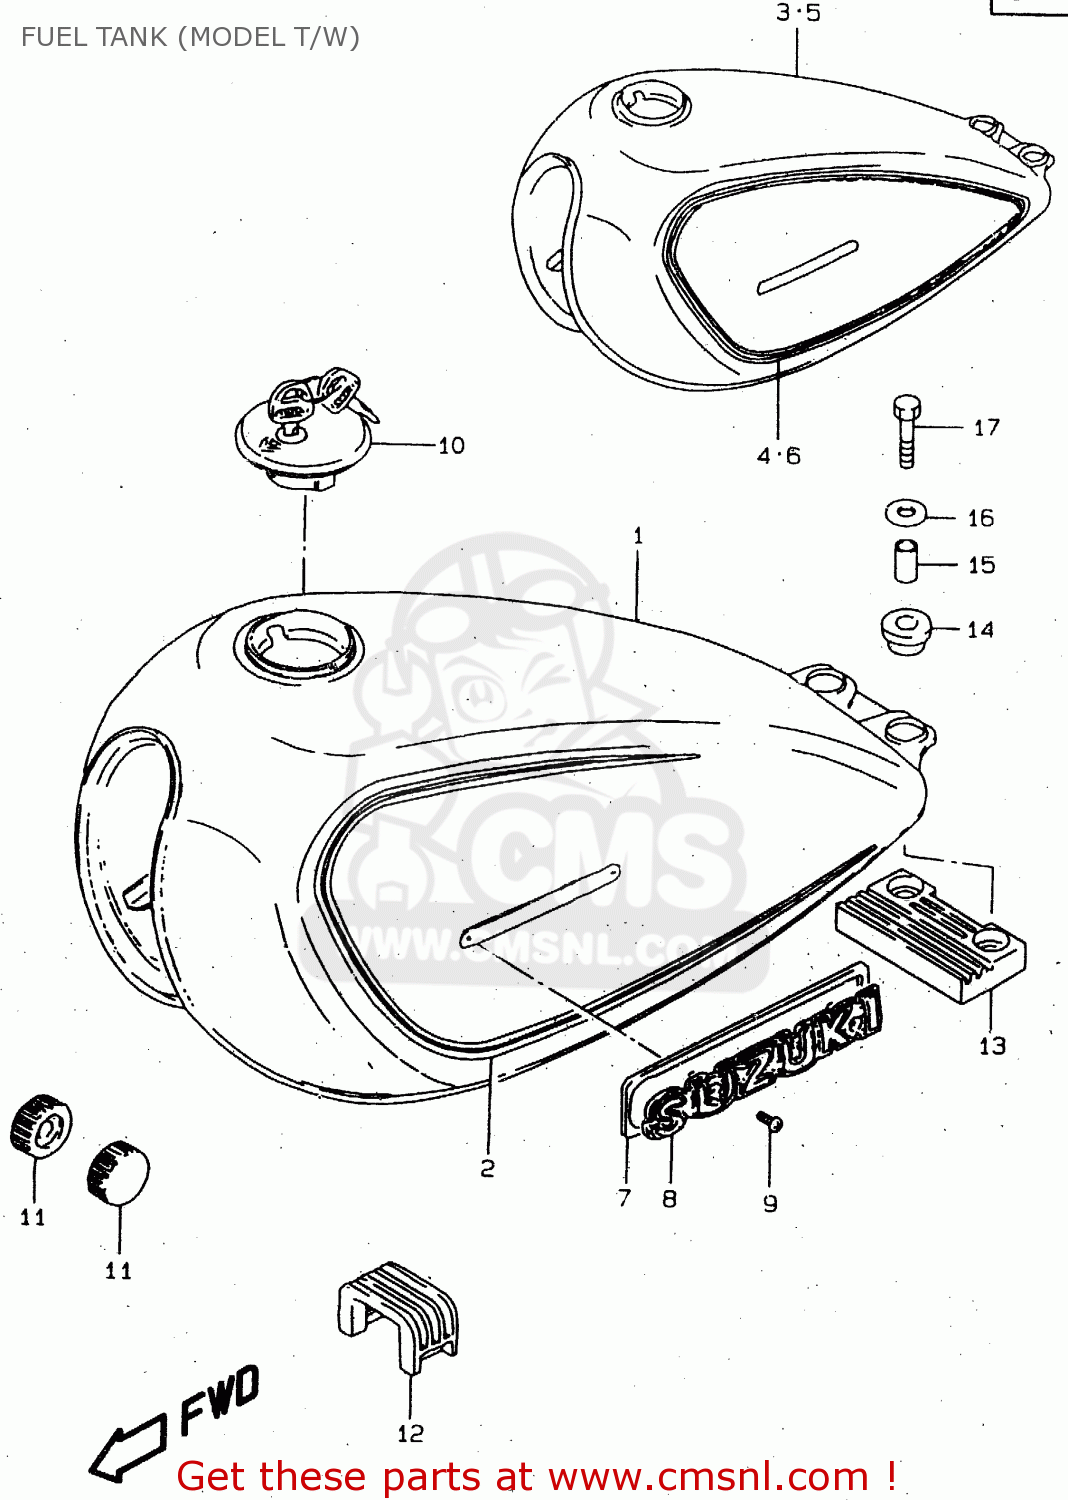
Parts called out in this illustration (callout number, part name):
1	TANK ASSY,FUEL
2	TAPE SET,FUEL TANK
3	TANK ASSY,FUEL(MAROON)
4	TAPE SET,FUEL TANK
5	TANK ASSY, FUEL (RED)
6	TAPE SET, FUEL TANK
7	CUSHION
8	EMBLEM,FUEL TANK
9	SCREW
10	CAP SET,FUEL TANK
11	CUSHION
12	CUSHION,TANK UPR FR
13	CUSHION,TANK RR NO.1
14	CUSHION
15	SPACER(6.5X10.5X22.5)
16	WASHER(6.5X22X1.6)
17	BOLT(6X35)
